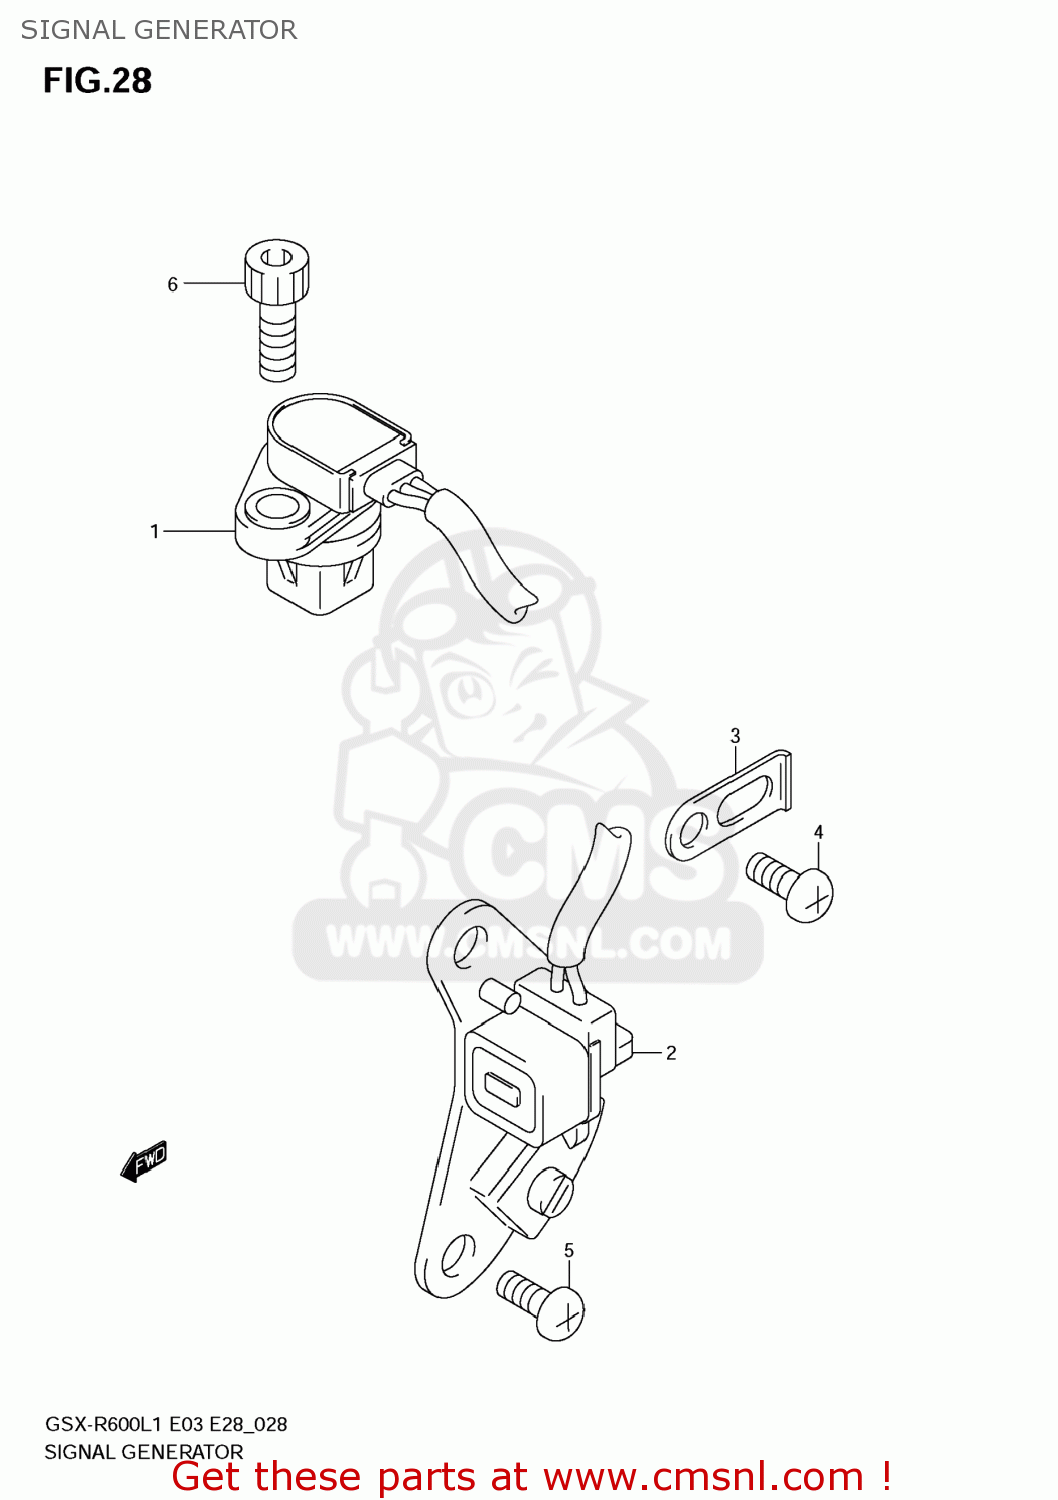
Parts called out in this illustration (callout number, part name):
1	SENSOR ASSY,CAM POSITION
2	STARTER,SIGNAL GENERATOR
3	CLAMP,SIGNAL GENERATORERATOR
4	BOLT
5	BOLT
6	BOLT
